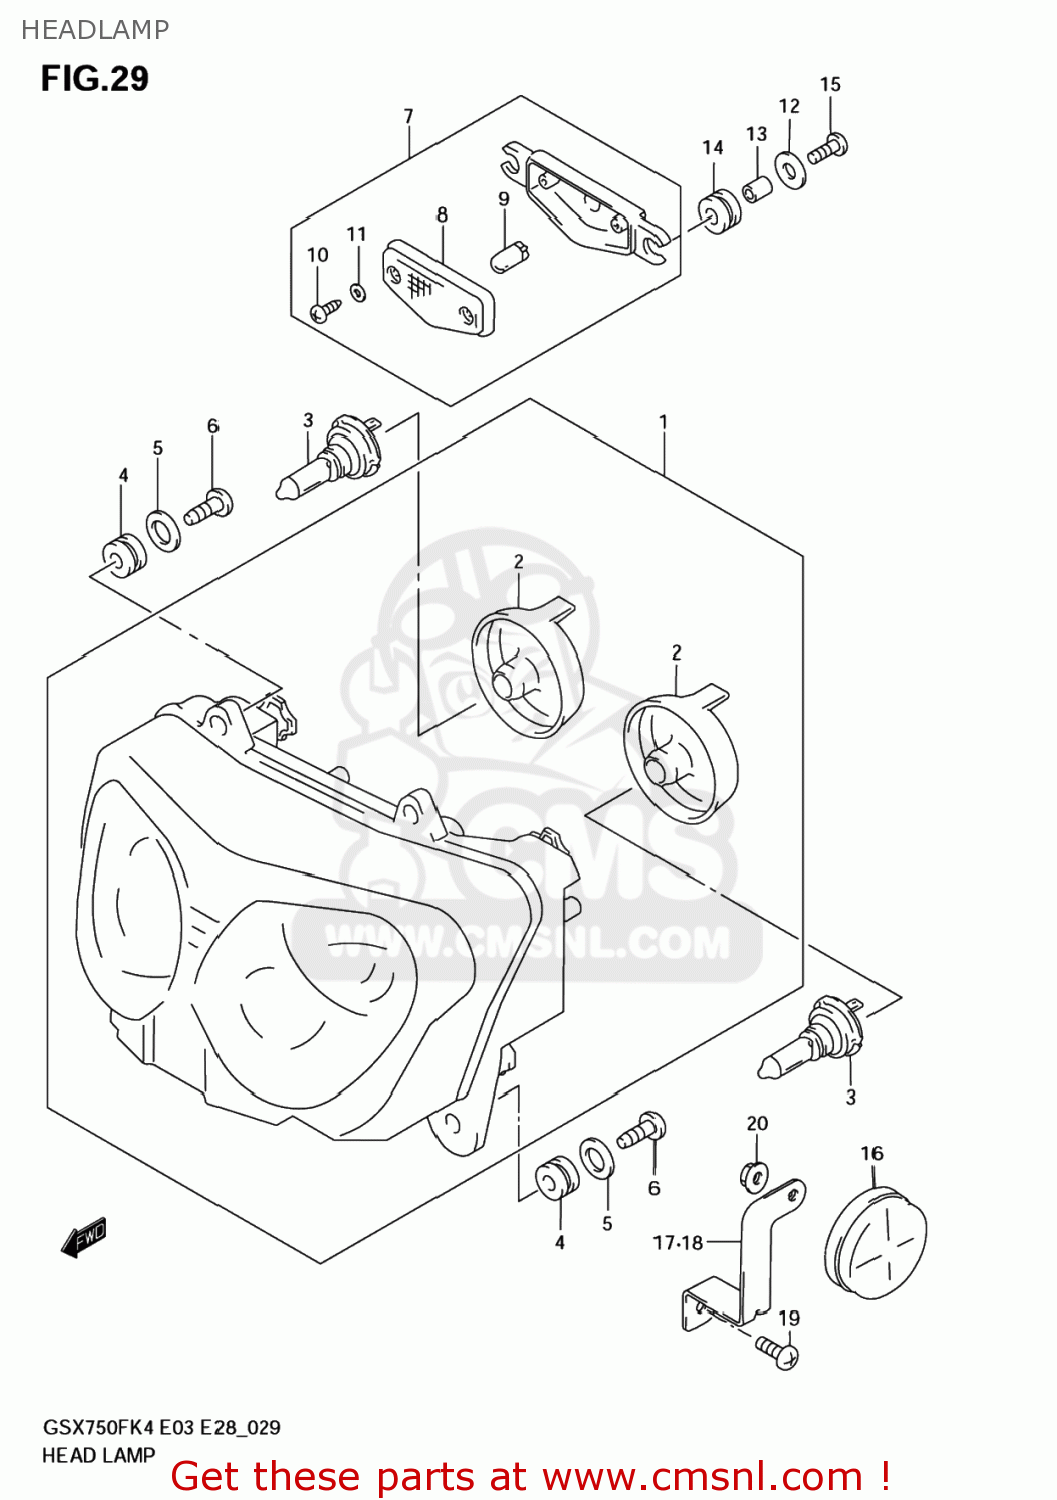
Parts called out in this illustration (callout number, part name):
1	HEADLAMP ASSY
2	COVER,SOCKET
3	BULB(12V60/55W,H4)
4	CUSHION,HEADLAMP
5	WASHER(5.5X18X1)
6	SCREW
7	LAMP ASSY,FR POSITION
8	LENS
9	BULB(12V5W)
10	SCREW
11	WASHER
12	WASHER(5.5X18X1)
13	SPACER(5.5X8X10.5)
14	CUSHION
15	SCREW 5X20
16	REFLECTOR,REFLEX FR
17	BRACKET,FR SIDE
18	BRACKET,FR SIDE RR,L
19	SCREW
20	NUT
